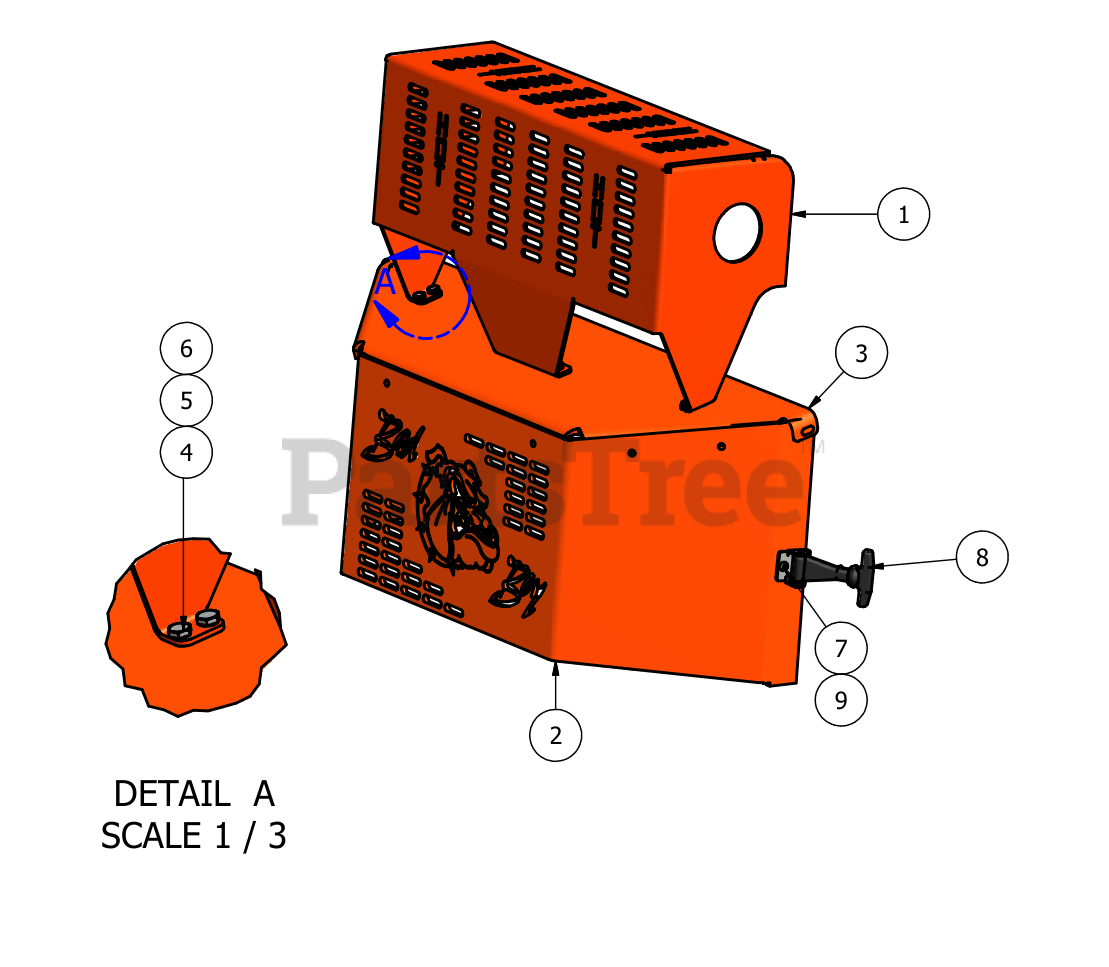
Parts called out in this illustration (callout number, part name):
1	Muffler Guard (35hp)
2	Pump Cover (35hp)
3	Top Pump Cover
4	1/4" x 3/4" SS Buttonhead Bolt
5	1/4" Lock Washer
7	1024 x 3/4" Buttonhead Bolt
8	Cover Latch
9	1024 Nylock Nut
